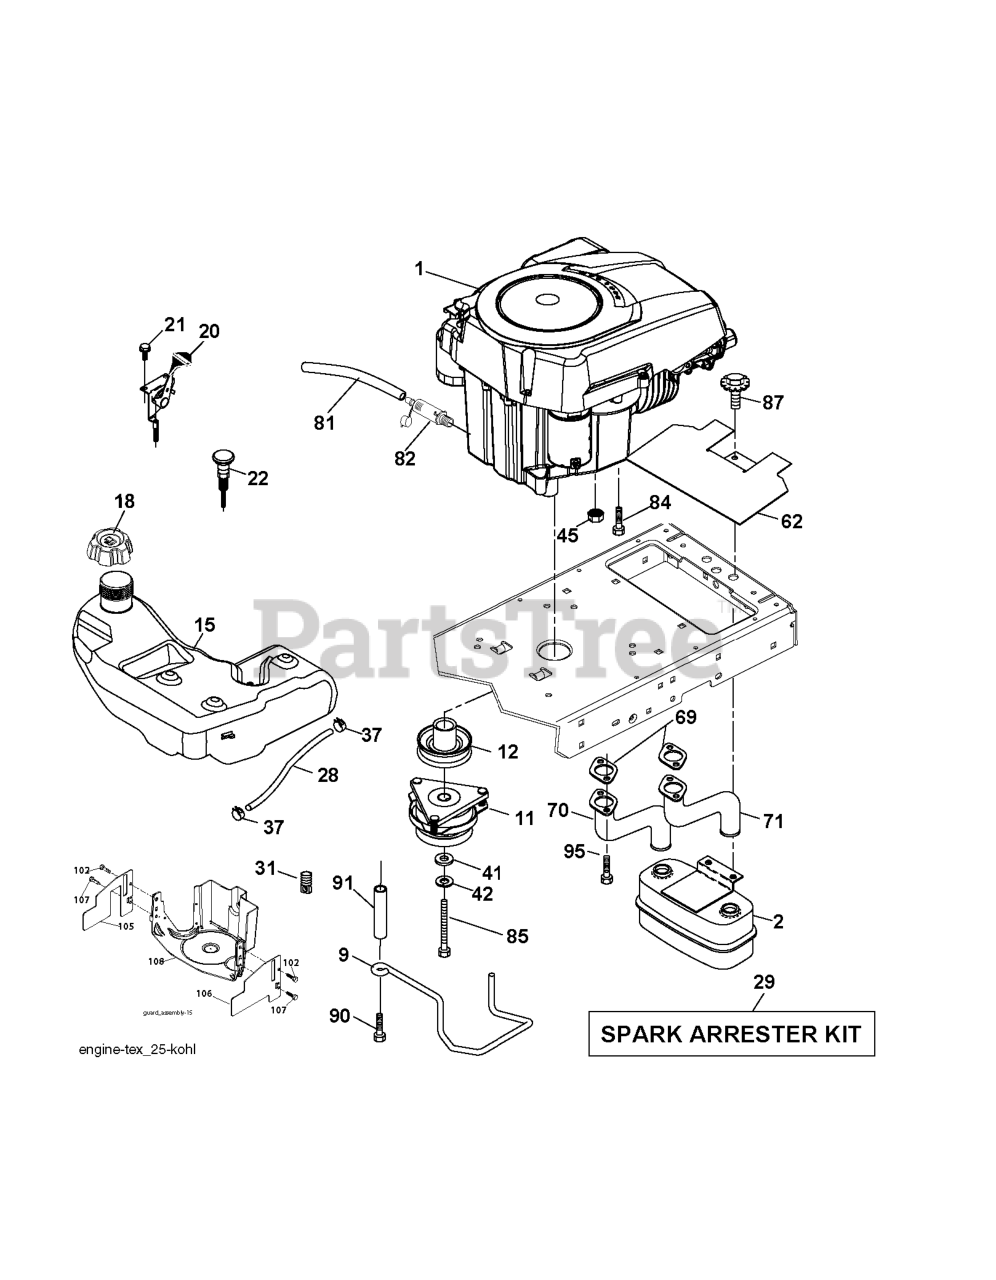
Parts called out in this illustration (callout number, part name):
2	MUFFLER.TWIN.CYL.LOW.TONE
9	KEEPER.BELT.ENGINE.3.25 (3 2)
11	CLUTCH MZ ZTR GT.48/54"1.125"
12	PULLEY.ASM.ENGINE.1-1/8X3-1/4
15	TANK.FUEL.4GAL
18	CAP.FUEL.TANK.3"GREY
20	THROTTLE CONTROL
21	SCREW
22	CONTROL.CHOKE.ERGO.PUSH-IN.BLA
28	REPL BY 532 00 85-43
29	KIT.SPARK ARRESTOR 794945 B&S
37	HOSE CLAMP
42	LOCKWASHER
45	NUT
62	RP SHIELD HEAT MUFFLER
70	RP.PIPE-EXHAUST LH
71	RP.PIPE-EXHAUST RH
81	TUBE, DRAIN OIL ASM.
82	PLUG DRAIN OIL EASY
84	SCREW 3/8-16X1
85	BOLT HEX 7/16-20 X 3.75 GR. 5
87	BOLT.5/16-18UNCX1.W/SEMS.BLK
90	SCREW 3/8-16X1
91	BUSHING.1.375OD
95	SCREW.SOCKET HD.5/16-1
102	SCREW
105	SHIELD SIDE
106	SHIELD SIDE
107	SCREW.1/4-20X5/8
